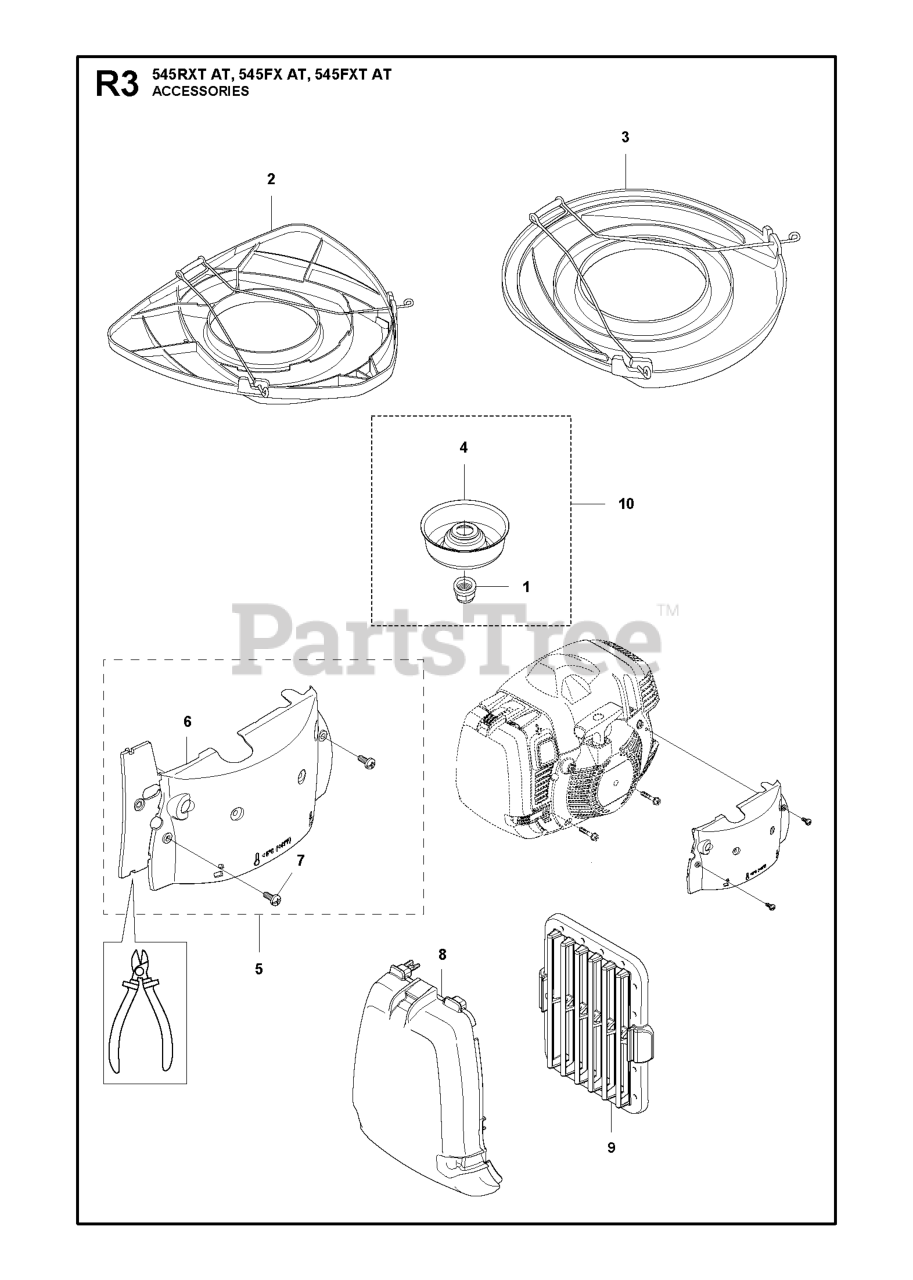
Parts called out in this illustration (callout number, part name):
2	TRANSPORT GUARD
3	BLADE GUARD TRANSPORT
4	SUPPORT CUP
5	WINTER KIT
6	WINTER COVER
8	WINTER COVER
